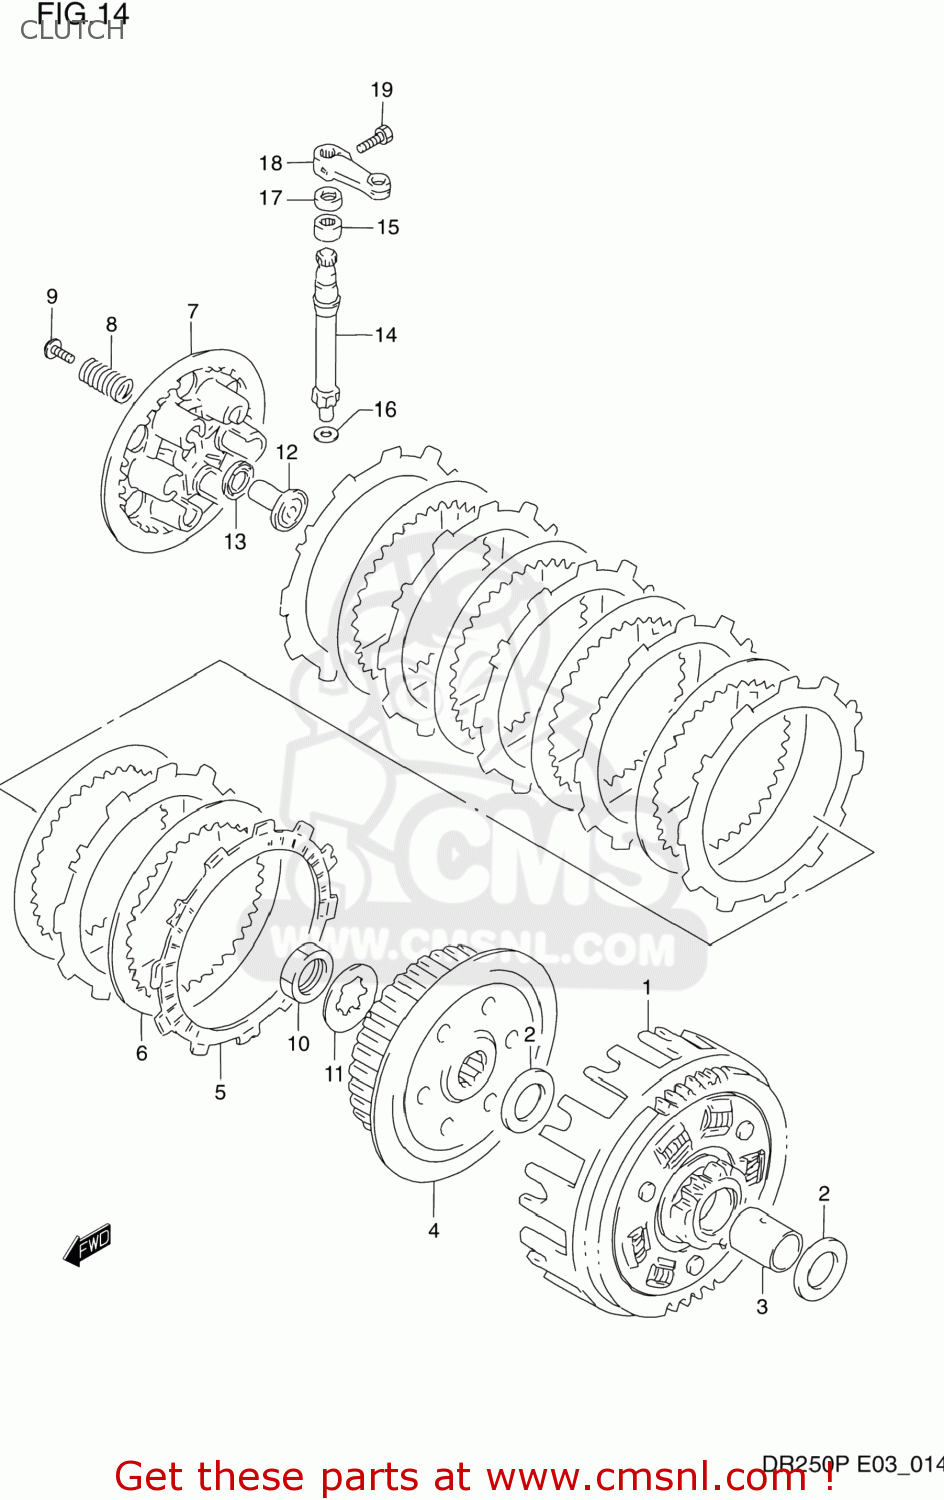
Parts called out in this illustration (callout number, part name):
1	GEAR ASSEMBLY,PRIMARY DRIVE
2	WASHER
3	SPACER(20X25X29)
4	HUB,CLUTCH SLEEVE
5	PLATE,CLUTCH DRIVE (NAS)
6	PLATE,CLUTCH DRIVEN (NAS)
7	DISC,CLUTCH PRESSURE
8	SPRING
9	BOLT 5X16
10	NUT (20MM)
11	WASHER,LOCK
12	RACK,CLUTCH RELEASE
13	BEARING(10X22X2.8)
14	PINION,CLUTCH RELEASE
15	BEARING(12X16X10)
16	WASHER
17	SEAL,OIL(10X17X5)
18	ARM,CLUTCH RELEASE
19	BOLT
